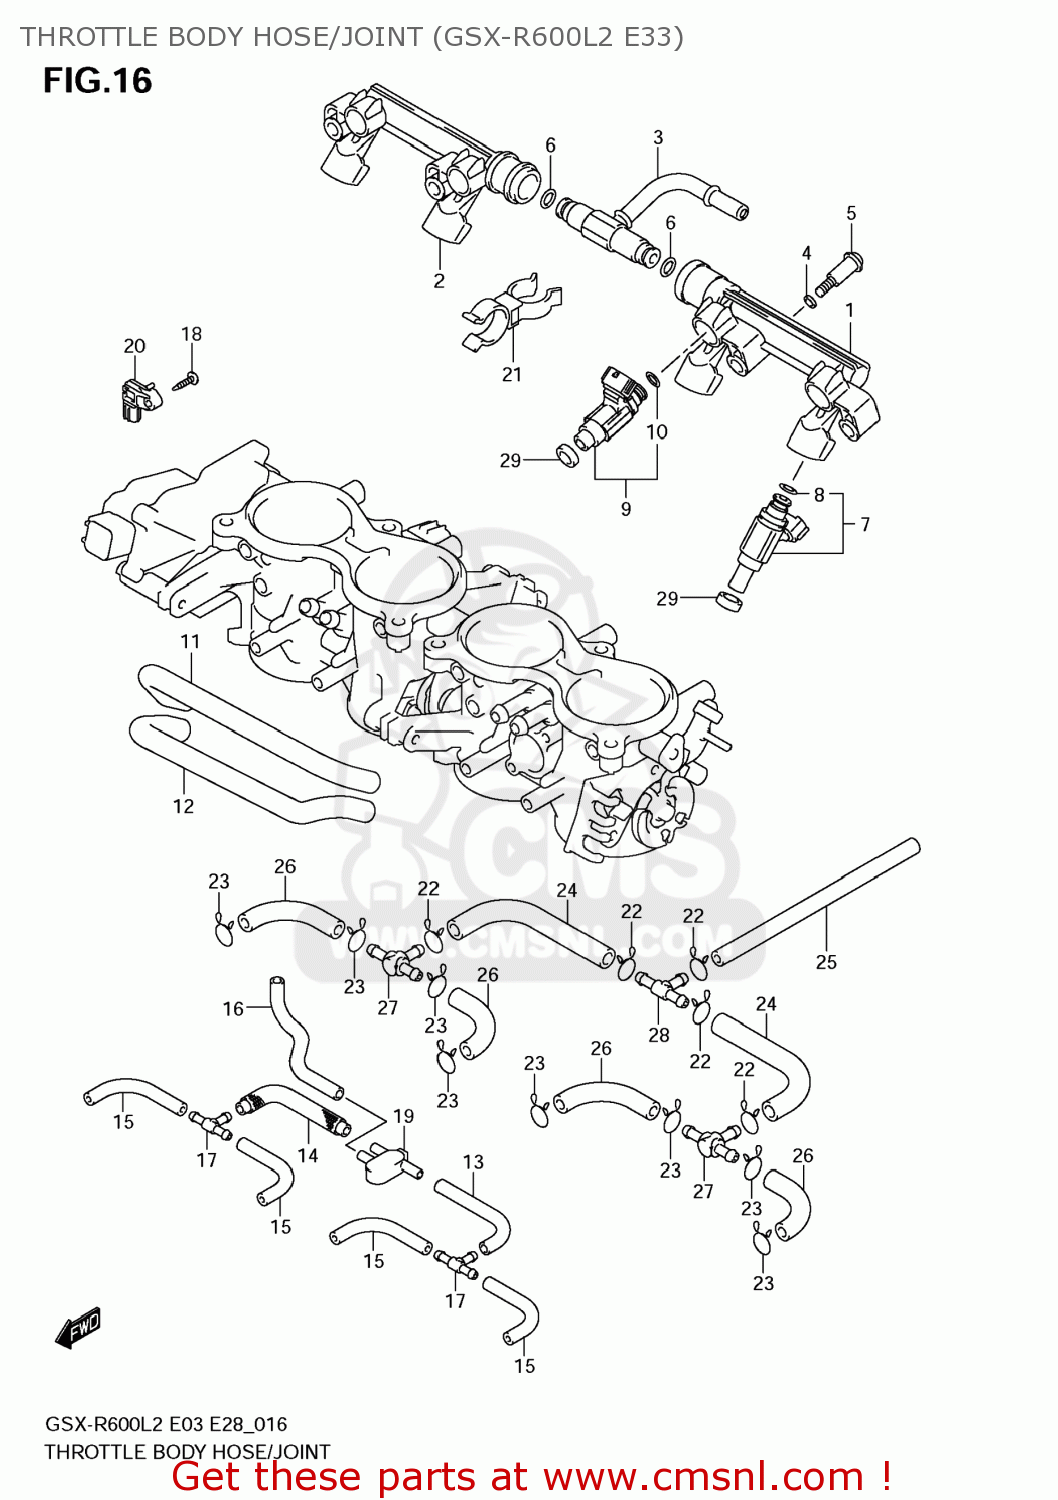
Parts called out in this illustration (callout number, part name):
1	DELIVERY PIPE
2	DELIVERY PIPE
3	NIPPLE ASSY
4	PACKING (NAS)
5	SCREW
6	O RING
7	INJECTOR ASSY
8	O-RING
9	INJECTOR ASSY
10	O-RING
11	HOSE
12	HOSE
13	HOSE
14	HOSE
15	HOSE(L:425)
16	HOSE
17	3WAY,VACUUM HOSE
18	SCREW
19	JOINT
20	SENSOR,BOOST
21	CLAMP
22	CLIP
23	CLIP
24	HOSE
25	HOSE
26	HOSE
27	NIPPLE
28	NIPPLE
29	SEAL
